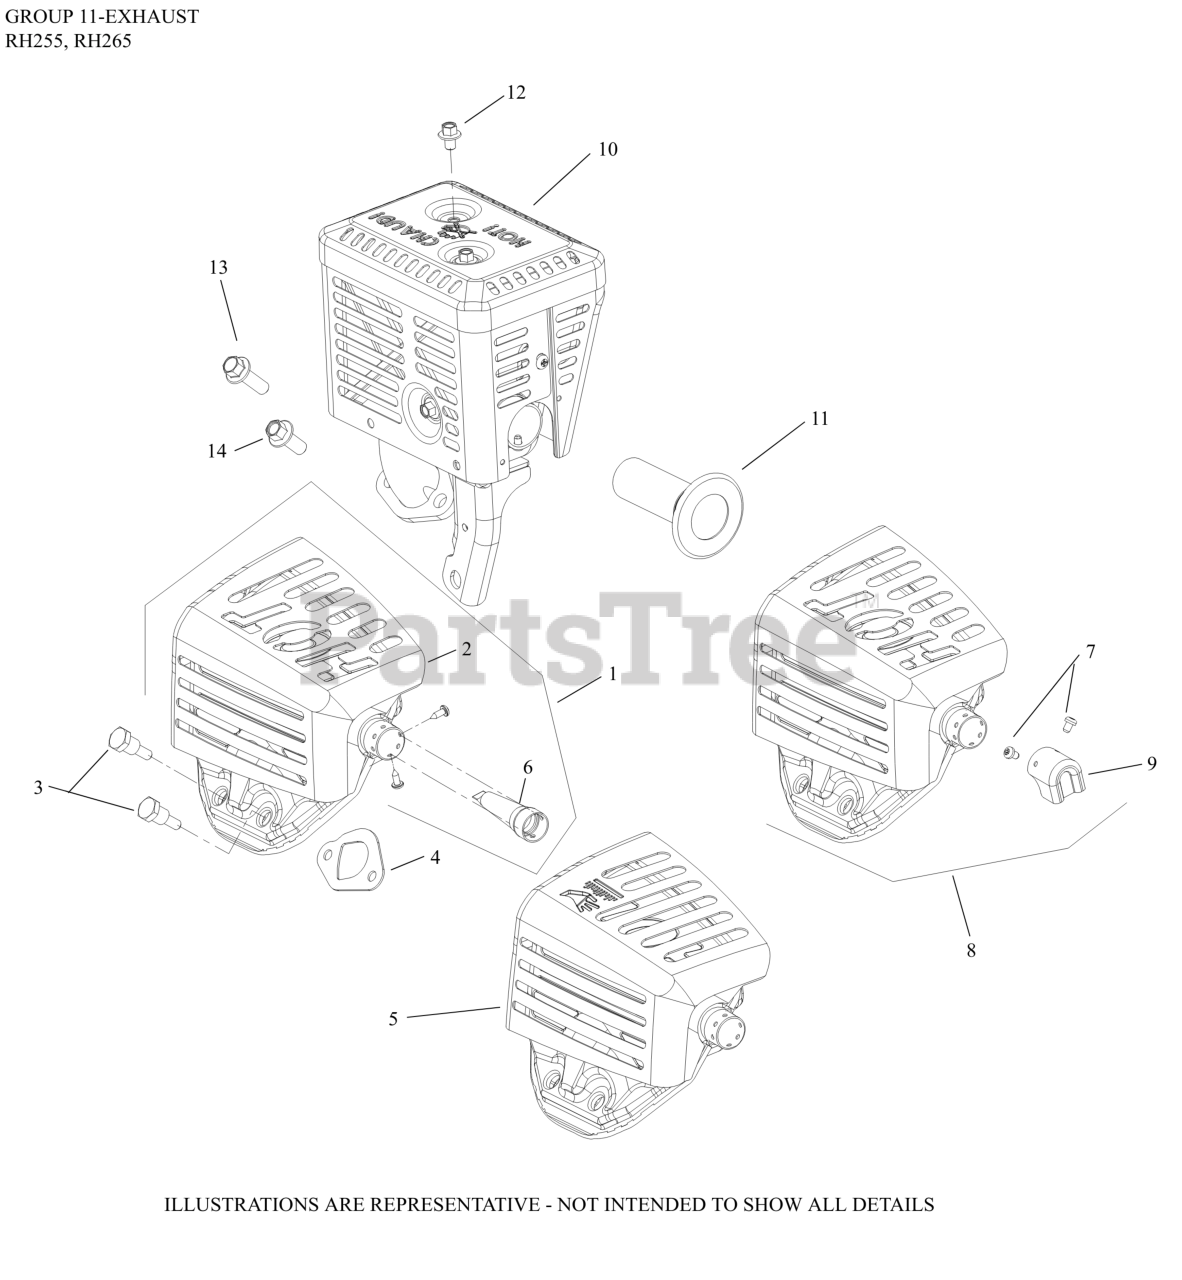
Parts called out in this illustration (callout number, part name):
2	MUFFLER ASSEMBLY
3	SCREW, SHOULDER
4	GASKET, MUFFLER
